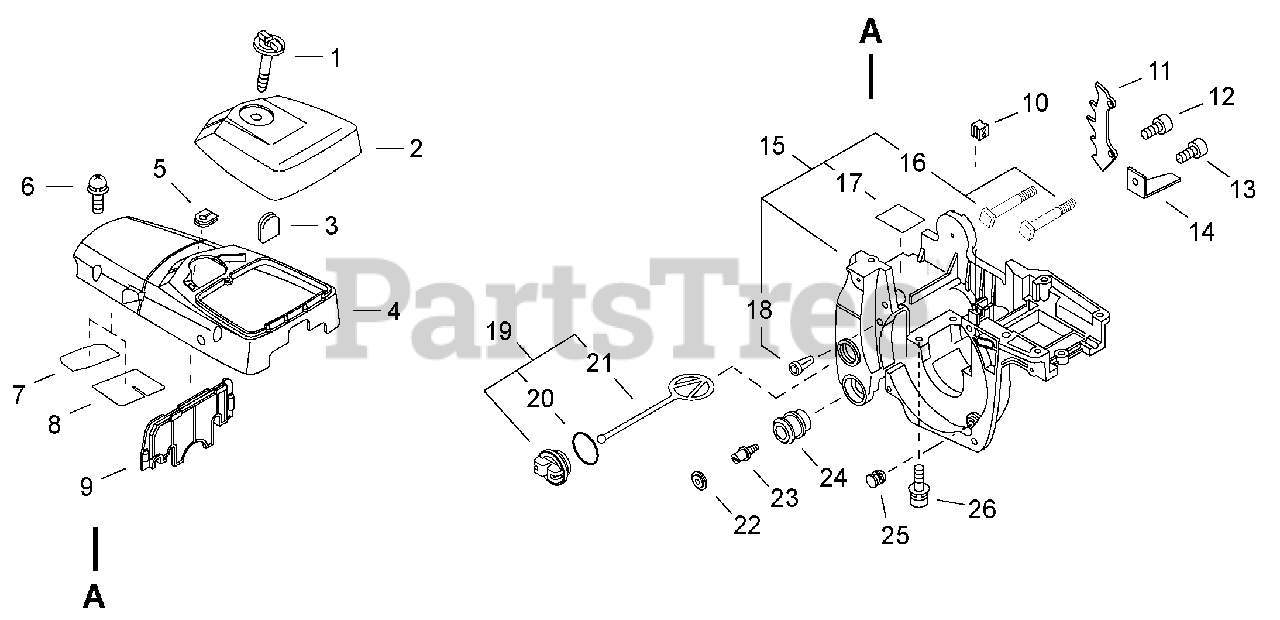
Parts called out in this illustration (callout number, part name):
1	THUMBSCREW
2	COVER, AIR FILTER
4	COVER, ENGINE
5	GROMMET
6	SCREW - 5X20
7	DEFLECTOR, HEAT
8	DEFLECTOR, HEAT
9	PLATE, INSULATOR
12	SCREW - 5X20 -- TAPPING
13	SCREW - 5X16
14	CATCHER, CHAIN
15	ENGINE COVER ASSY
16	STUD, GUIDE BAR
17	DEFLECTOR, HEAT
18	VENT, TANK
19	CAP ASSY - BLACK
20	O-RING - 25
21	CONNECTOR, CAP
22	CAP, CUSHION
25	CUSHION
26	SCREW - 5X30
